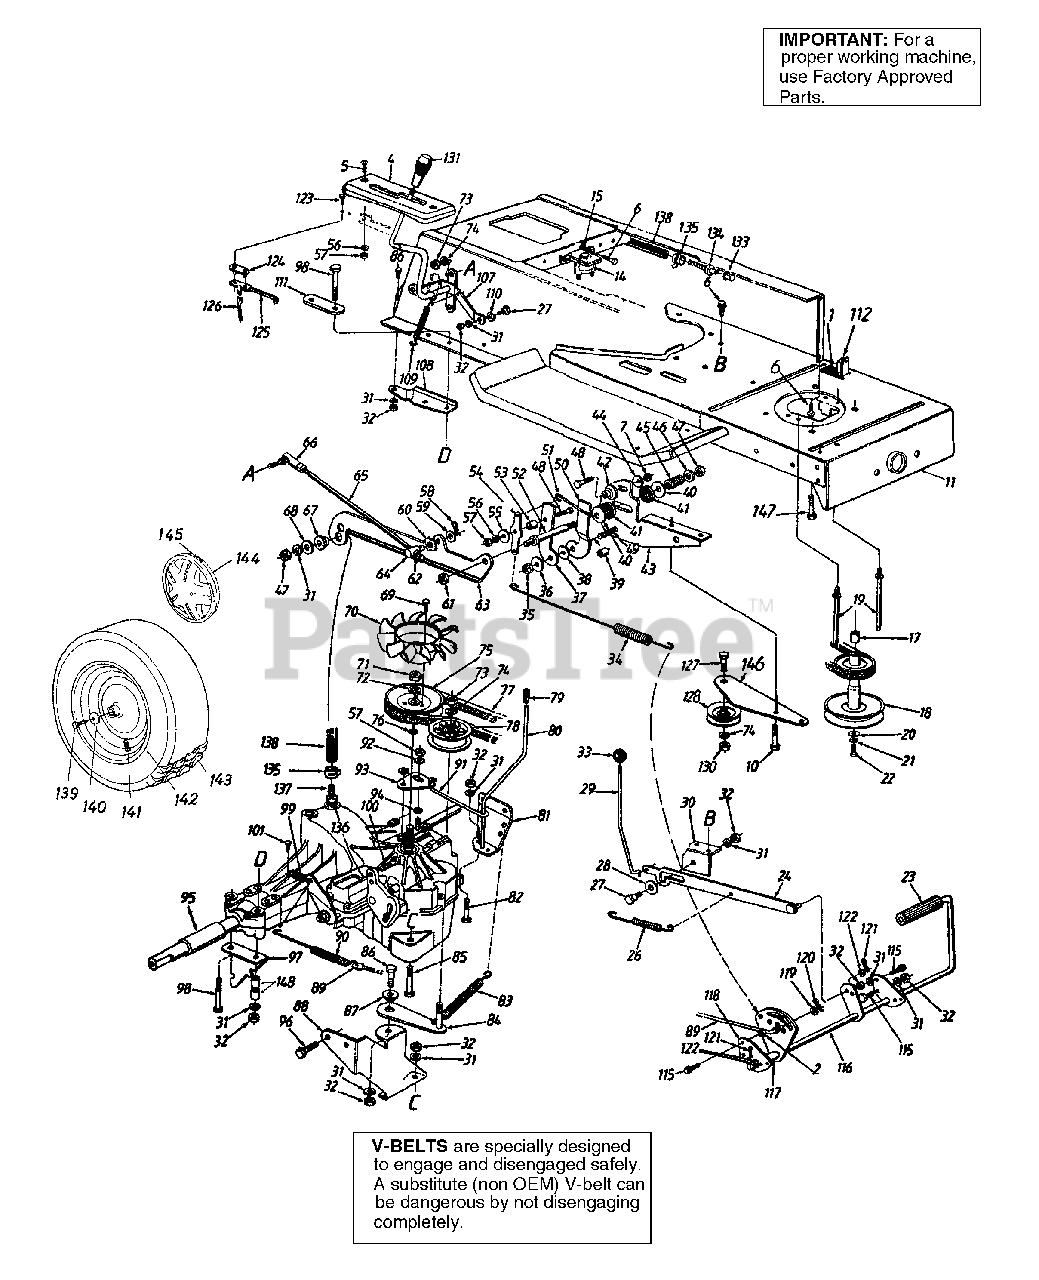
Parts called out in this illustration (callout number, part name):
1	Spring Switch
2	Hex Sems Nut 5/16-18 Thd.
4	Index Bracket
5	Pan Hd. Mach. Scr. 1/4-20 x .75" Lg.
6	Hex Wash. Hd. TT-Tap Scr. 1/4-20 x .5"
7	Hex Nut 1/4-28 Thd.
10	Hex. Bolt 1/4-28 x .62" Lg.
14	Solenoid
15	Ext. L-Wash. 1/4" I.D.
18	Engine Pulley
19	Belt Guard Stud 4.75" Lg.
20	Fl-Wash. 7/16" I.D. x 1.25" O.D.
21	L-Wash. 7/16" I.D.
22	Hex Bolt 7/16-20 x 1.5" Lg.
23	Foot Pad
27	Shld. Bolt .437" Dia. x .268"
28	Fl-Wash. 7/16" I.D. x 1-3/8" O.D.
29	Lock-up Rod
31	L-Wash. 5/16" I.D.
32	Hex Nut 5/16-18 Thd.
34	Neutral Return Spring
35	Hex Nut 5/16-24 Thd.
36	Fl-Wash. .344" I.D. x 1" O.D.
37	Scissor-Flat
38	Fl-Wash. .33" I.D. x 1.25" O.D.
40	Bell-Wash. .4" I.D. x 1.13" O.D.
41	Friction Washer
42	Centering Gauge Spacer
43	Neutral Return Mtg. Brkt.
44	Bell-Wash. .265" I.D. x .75" O.D.
45	Comp. Spring 1.19" Lg.
46	Fl-Wash. .26" I.D. x .72" O.D.
47	Hex Nut 5/16-24 Thd.
48	Hex Bolt 1/4-28 x 1" Lg. (Gr. 5)
49	Rib Neck Bolt 5/16-24 x .84" Lg.
50	Scissor - Offset
51	Neutral Return Rod
52	Friction Disc Stud
53	Shld. Spacer
54	Neutral Return Lever
55	Fl-Wash. .265" I.D. x 1" O.D.
56	L-Wash. 1/4" I.D.
57	Hex Nut 1/4-20 Thd.
58	Hairpin Clip
59	Fl-Wash. .375" I.D. x .87" O.D.
60	Spring Wash. .39" I.D.
61	Hex L-Nut 3/8-24 Thd.
62	Hex Jam Nut 3/8-24 Thd.
63	Neutral Return Brkt.
64	Ferrule 3/8-24 Thd.
65	Control Rod
66	Ball Joint 3/8-24 Thd.
67	Shld. Spacer .5" Dia. x .27" Lg.
68	Fl-Wash. .349" I.D. x .879" O.D.
69	Hex Tap Scr. #12 x .625" Lg.
70	Fan
71	Hex Nut 1/2-20 Thd.
72	L-Wash. 1/2" I.D.
73	Hex Nut 3/8-24 Thd.
74	L-Wash. 3/8" I.D.
75	Transmission Pulley
78	Fl-Idler Pulley 2.75" O.D.
79	Rod End Grip
80	Bypass Control Lever
83	Ext. Spring 6.12
85	Hex Bolt 5/16-18 x 2.5" Lg.
86	Hex Bolt 5/16-18 x .75" Lg.
87	Shld. Spacer .5" Dia. x .27" Lg.
90	Ext. Spring
91	Bypass Actuator Rod
92	Fl-Wash. .281" I.D. x .5" O.D.
93	Bypass Adjustment Brkt.
94	External L-Wash. 1/4" I.D.
95	Sleeve .758" I.D. x 1" O.D.
96	Hex. TT-Tap Scr. 5/16-18 x .62"
99	Tension Spring
100	Hex Bolt 5/16-24 x 1" Lg.
101	Hex Wash. Hd. AB-Tap Scr. #10 x .5" Lg.
107	Speed Control Lever Ass'y.
110	Spr-Wash. .445" 1.0. x .75" O.D.
112	Safety Switch (Clutch)
115	Hex TT-Tap Scr. 5/16-18 x .75"
120	Cotter Pin 3/32" Dia.
121	Cotter Pin 1/8" Dia.
122	Fl-Wash. .385" I.D. x .62" O.D.
123	Hex AB-Tap Scr. #8 x .5" Lg.
124	Insulator Nut Plate
125	Reverse Safety Switch
126	Extension Wire
127	Hex Bolt 3/8-16 x 1.5" Lg.
128	Idler Pulley
130	Hex Nut 3/8-16 Thd.
134	Plastic Vent
135	Clamp
137	Hose Fitting
138	Fuel Line 20" Lg.
139	Hex Bolt 5/16-24 x .75" Lg.
140	Bell-Wash. .345" I.D. x .88" O.D.
141	Air Valve
148	Spacer .32" x .75"
